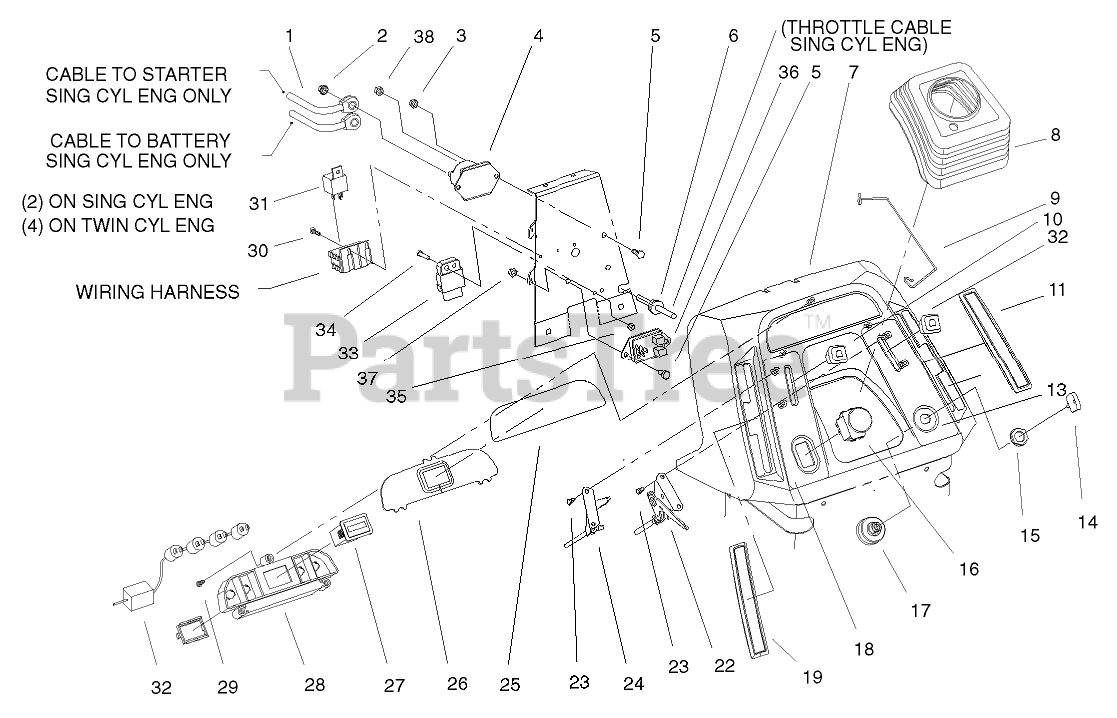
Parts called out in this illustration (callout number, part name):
1	BOOT-STEERING
2	RETAINER-BOOT
3	SCREW-PPH
4	LENS-DASH
5	DECAL - DASH LENS
6	HOUSING-LIGHT, DASH
7	KEY-IGNITION
9	HOURMETER
10	SWITCH-PTO
11	SWITCH-IGNITION
12	SCREW-PPHTF
13	KNOB-THROTTLE
15	THROTTLE CONTROL ASM
16	CHOKE CONTROL ASM
17	KNOB-CHOKE
19	SCREW-HH
20	GASKET-FOAM
21	GAUGE - WATER TEMP WC
22	GAUGE-FUEL
23	HARNESS-7 LIGHT,WC
24	Guard-Latch (Only On: 73580)
